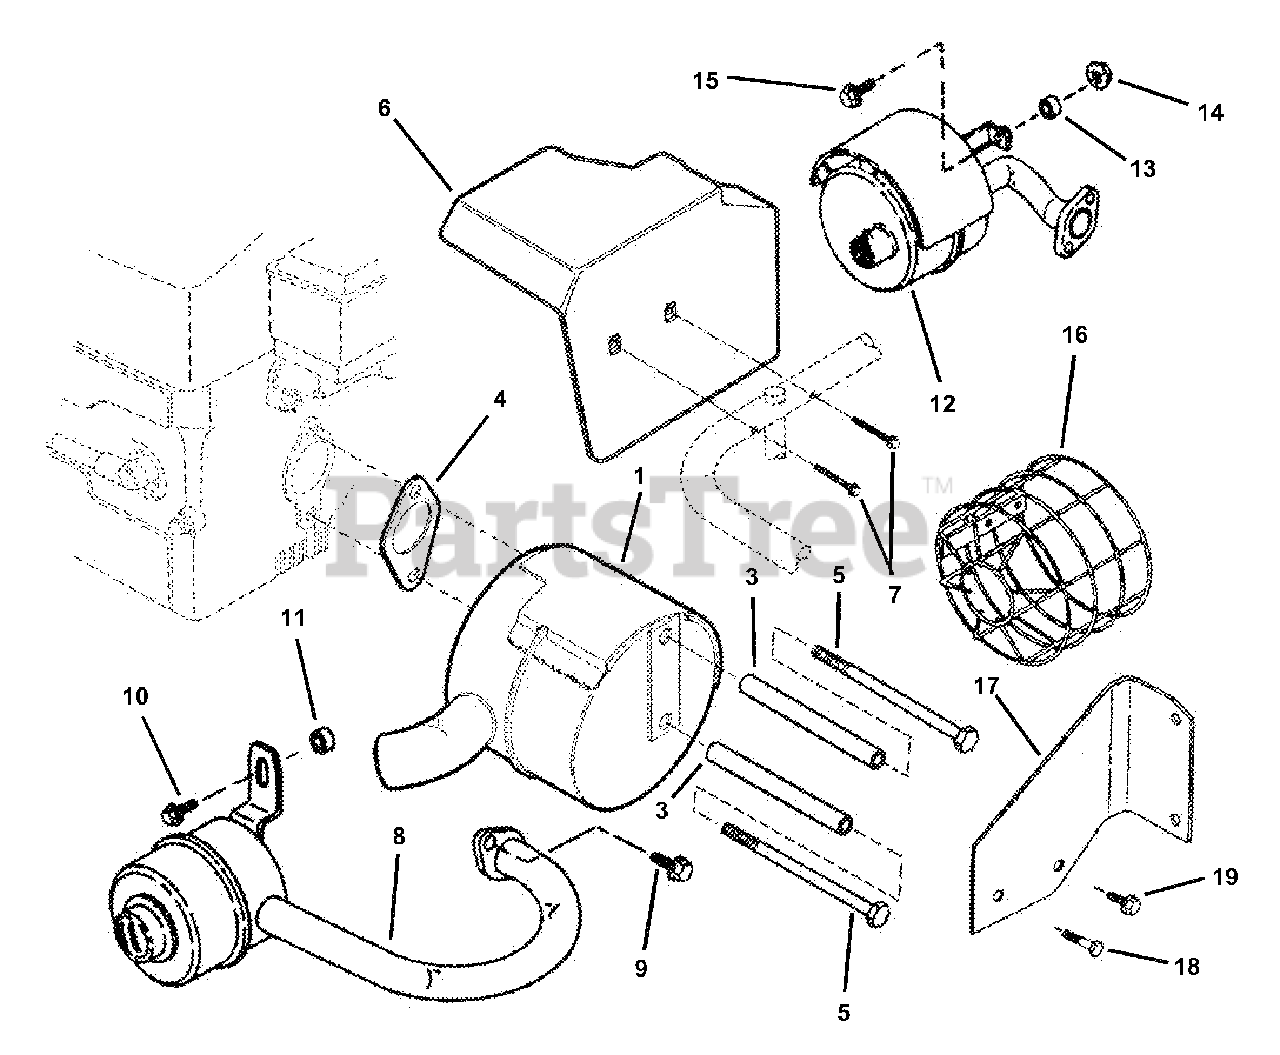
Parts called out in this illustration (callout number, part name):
1	MUFFLER, 12HP Wisconcin Robin
2	HARDWARE BAG
3	SPACER, .312 I.D. x 3-1/2"
4	GASKET, Exhaust (Robin 12HP)
5	SCREW, 5/16-18 x 4-1/4" Hex Head Cap
6	ASSEMBLY, Heat Shield
7	SCREW, #10-32 x 1-1/2" Hex Washer Head
8	MUFFLER, 12HP Wisconcin Robin
9	SCREW, 5/16-18 x 3/4" Hex Head Cap
10	SCREW, 1/4-20 x 3/4" Hex Head Cap
11	SPACER
12	MUFFLER, 14/15HP Kohler
13	SPACER, .33 x .63 x .156
14	NUT, 1/4-20 Hex Flange Lock
15	SCREW, 1/4-20 x 3/4" Hex Head Cap, Grade 5
16	GUARD, Muffler (Kohler)
17	BRACKET, Muffler Guard (Kohler)
18	SCREW, 1/4-20 x 1" Hex Head Cap, Grade 5
19	SCREW, 1/4-20 x 5/8" Hex Head Self-Tap
